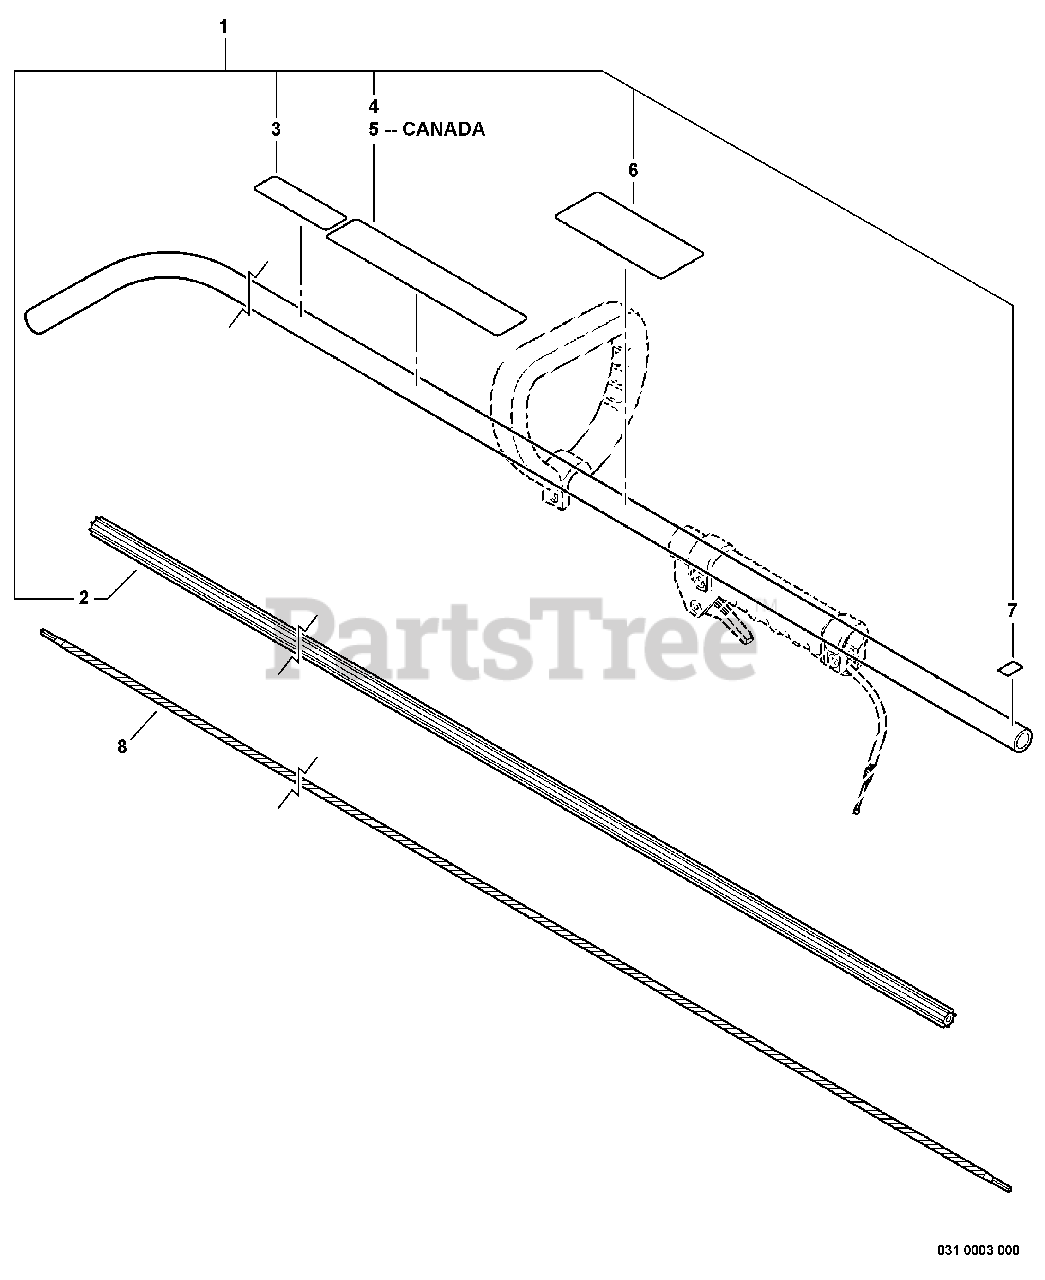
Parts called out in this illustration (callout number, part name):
1	MAIN PIPE ASSY
2	LINER - FLEXIBLE
3	LABEL, CAUTION
4	LABEL, CAUTION
5	LABEL - CAUTION
6	LABEL, HANDLE LOCATION
7	LABEL - ALIGNMENT
8	DRIVESHAFT - FLEXIBLE
